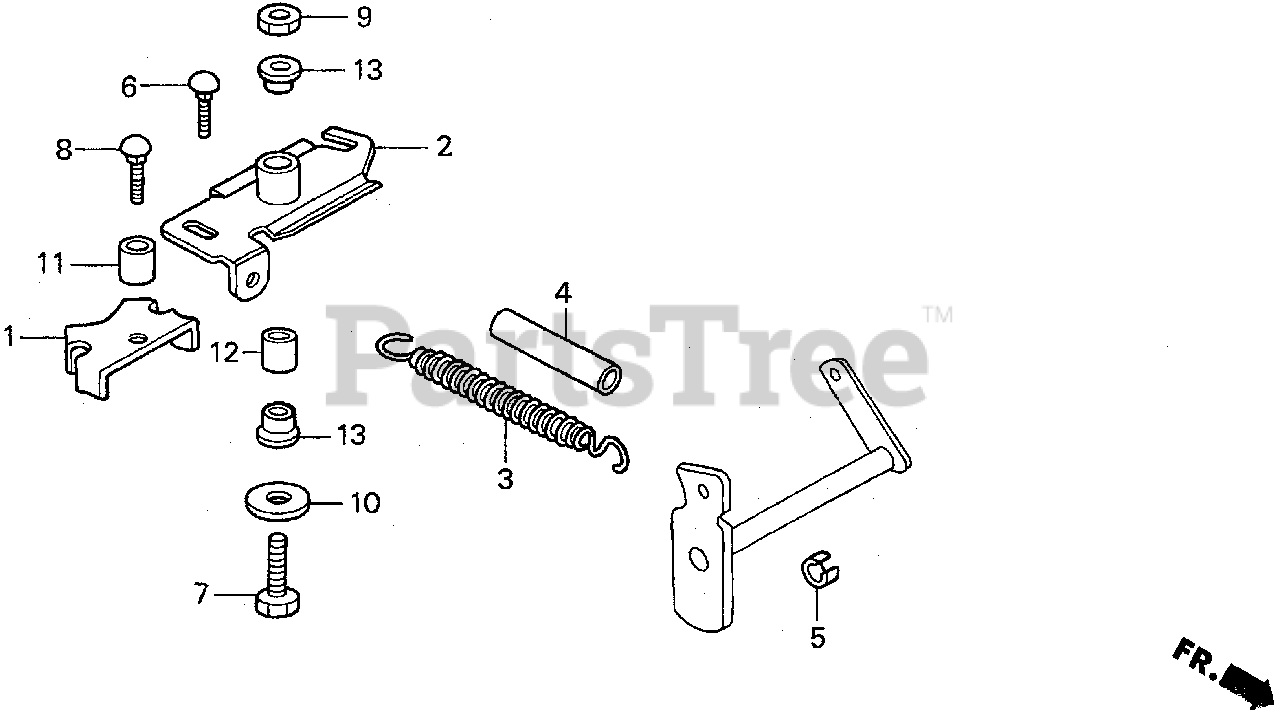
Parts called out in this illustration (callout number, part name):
1	STOPPER D, BELT
2	ARM, TENSIONER
3	SPRING, BELT TENSIONER
4	COVER, SPRING
5	COLLAR, PEDAL
6	BOLT, CARRIAGE (10X45)
7	BOLT, HEX. (10X50)
8	BOLT, CARRIAGE (10X65)
9	NUT, FLANGE (10MM)
10	WASHER, CONSOLE
11	BUSHING, IDLER PULLEY
12	BUSHING, PIVOT (INNER)
13	BUSHING, DRIVE
